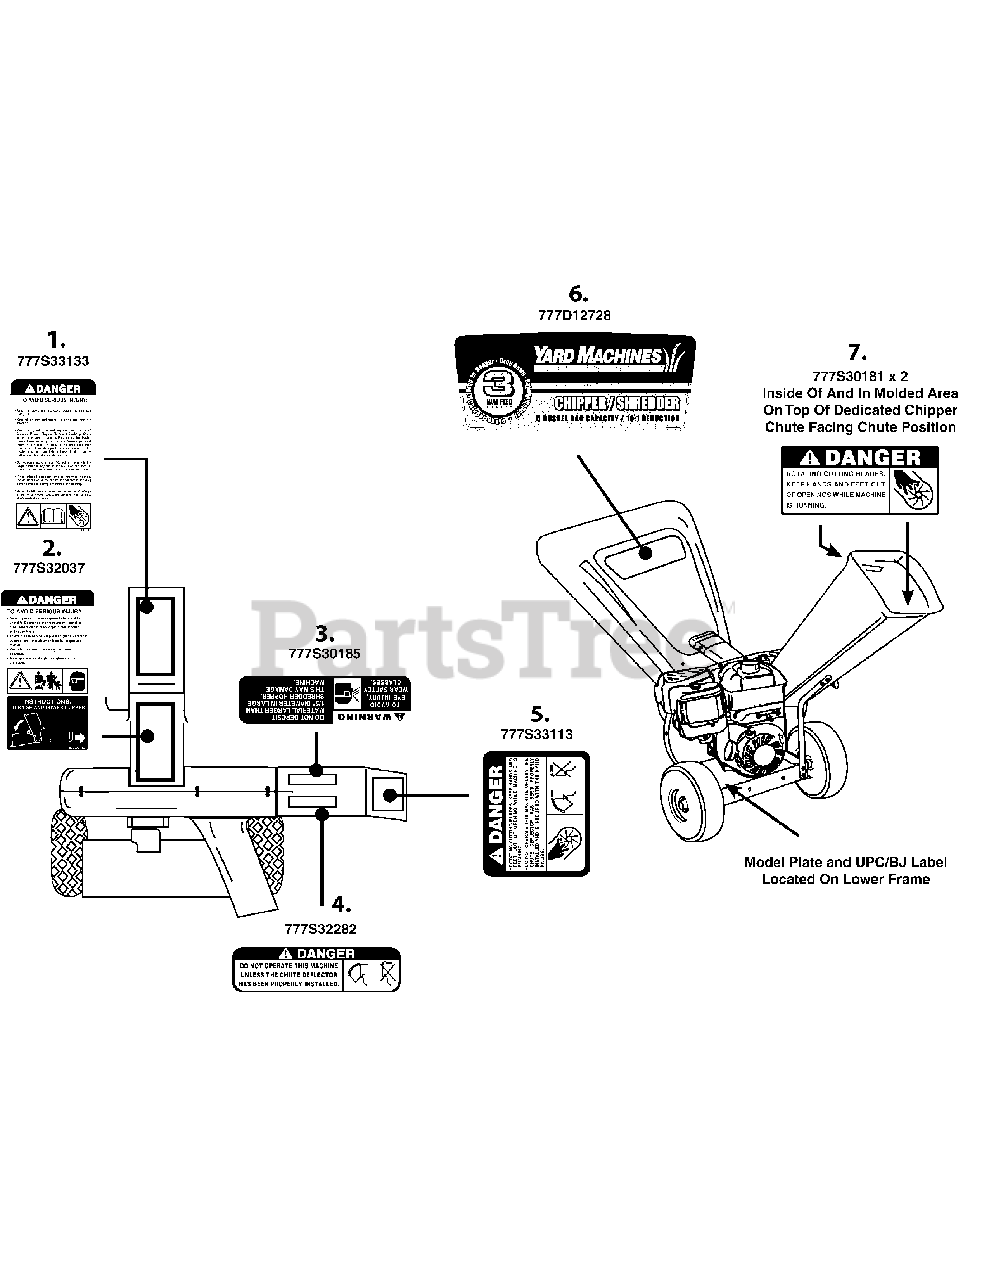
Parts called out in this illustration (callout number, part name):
1	LABEL-CS:400:LGCHUTE:DANGER
2	LABEL-DANGER CHIPP
3	LABEL-CHP/SHRD
4	LABEL-CHUTE
5	LABEL-CHIPPER SHREDDER CHUTE
6	LABEL-CS:HOPR:YMRED:464_3WAY
7	LABEL-TOP CHUTE DANGER
